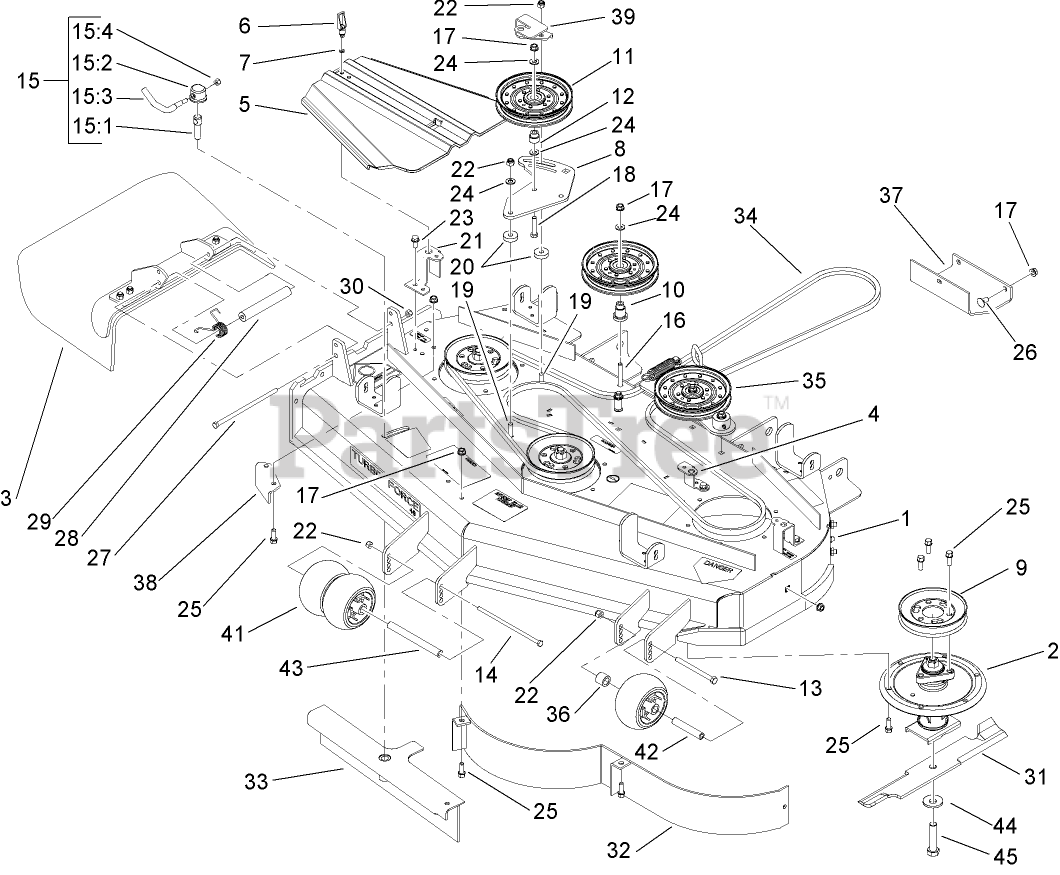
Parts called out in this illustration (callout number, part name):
1	DECK DECAL ASM
2	SPINDLE ASM
3	RUBBER DEFLECTOR ASM
4	BRACKET-COVER, TALL
5	COVER-BELT
6	LATCH-SWELL
7	WASHER
8	PLATE-IDLER
9	PULLEY
10	MOUNT-PULLEY
11	Idler-Flat
12	BUSHING-IDLER
13	SCREW-HH
14	SCREW-HH
15	LEVER ASM
15:1	Screw-Lock
15:2	CAP-LOCK
15:3	Lever-Lock
15:4	NUT-LOCK, NI
16	SCREW-HH
17	NUT-HHF, WHIZ
18	SCREW-HH
19	SCREW-CARR
20	Spacer
21	BRACKET-COVER
22	NUT-LOCK, NI
23	SCREW-HWHTF
24	WASHER-FLAT
25	SCREW-HWH
26	SCREW-CARR
27	SCREW-HH
28	SPACER
29	SPRING-TORSION
30	NUT-LOCK, NI
31	BLADE-16.5 INCH (HIGH FLOW)
32	BAFFLE ASM
33	BAFFLE
34	BELT-V
35	SPRING IDLER ASM
36	TUBE-SPACER
38	BAFFLE-DISCHARGE
39	BRACKET-COVER
41	ROLLER-SCALP, ANTI
42	TUBE-SPANNER
43	SPACER-WHEEL
44	Washer-Blade Bolt, Heavy
45	Screw-Cap
